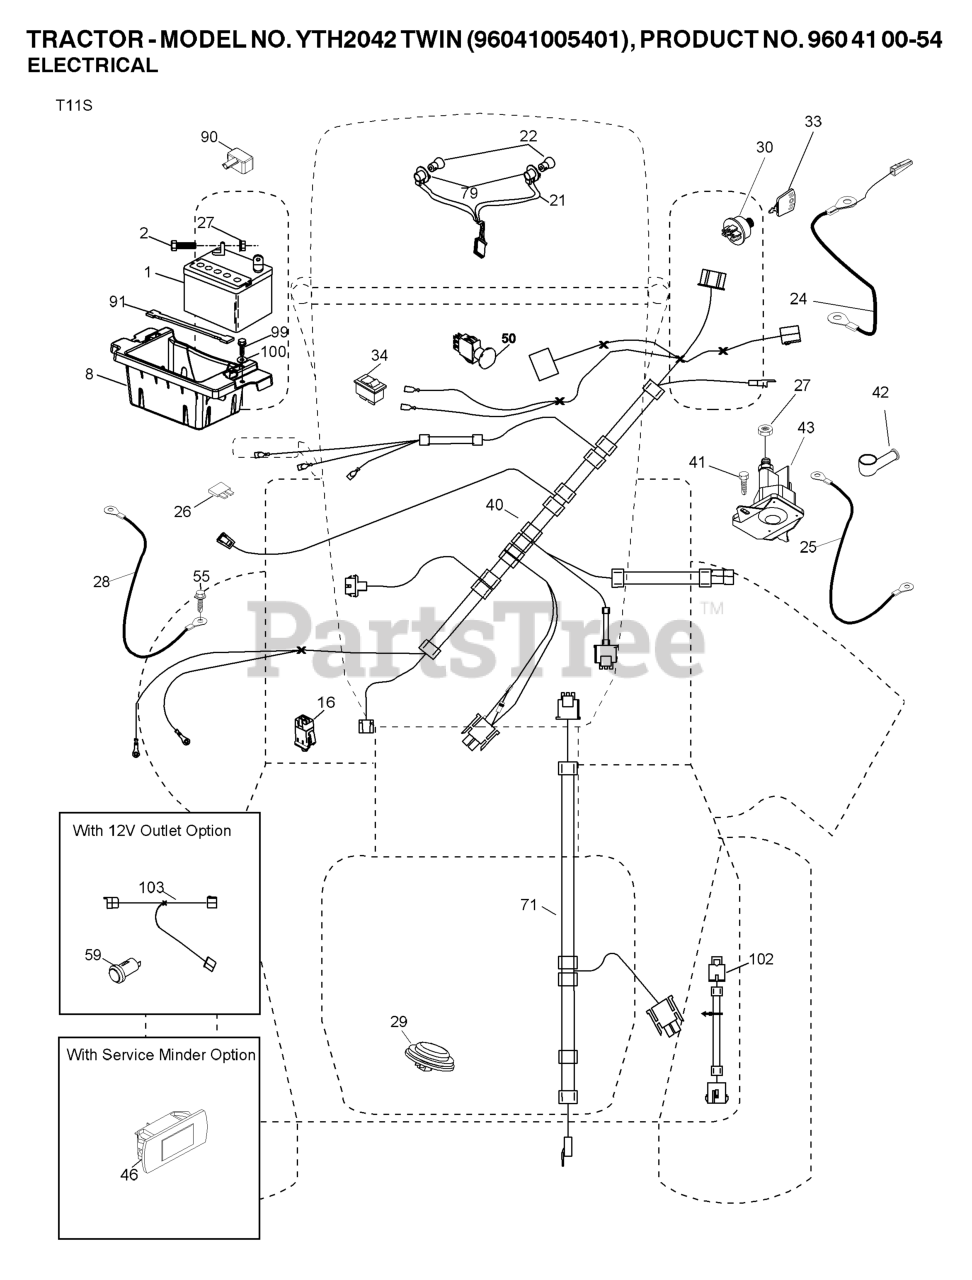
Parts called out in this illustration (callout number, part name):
1	Battery 12 Volt 25 Amp
2	BOLT.HEX.1/4.X.3/4.DICHROMATE
8	BOX.BATTERY.MOUNT.FRONT.LT
16	SWITCH INTERLOOK PUSH-IN
21	HARNESS ASSY LIGHT
24	CABLE.BATT.POS.WIRE.TG.DA SOL
25	CABLE.STARTER.6G.BL/RED.17.5
26	FUSE 20AMP
27	NUT
28	CABLE GROUND 6 GA 21" 90T BLK
29	SWITCH.SEAT.DELTA.OPC.
30	SWITCH.IGN.DELTA.W.LGH.ROS
33	KEY.CHAIN.BLISTER.PACK.GEN.USA
40	HARNESS.IGN.DASH.HUQ/P
41	SCREW
42	TERMINAL COVER
43	SOLENOID.W/BRASS.PLUNGER
50	RP.PTO.SWITCH.8 TERMINAL.BLACK
55	SCREW 5/16"
59	OUTLET.12-VOLT
71	HARNESS-CHASSIS SUB
79	BULB HOLDER ASM.
90	COVER.TERMINAL.BATTERY
91	STRAP.BATTERY.MOUNT.FRONT(2 2)
99	SCREW HEXWSHR 1/4-20X3/4
102	HARNESS PIGTAIL PCH TEX ROS
103	HARNESS PIGTAIL 12V OUTLET
105	REVERSE SWITCH
